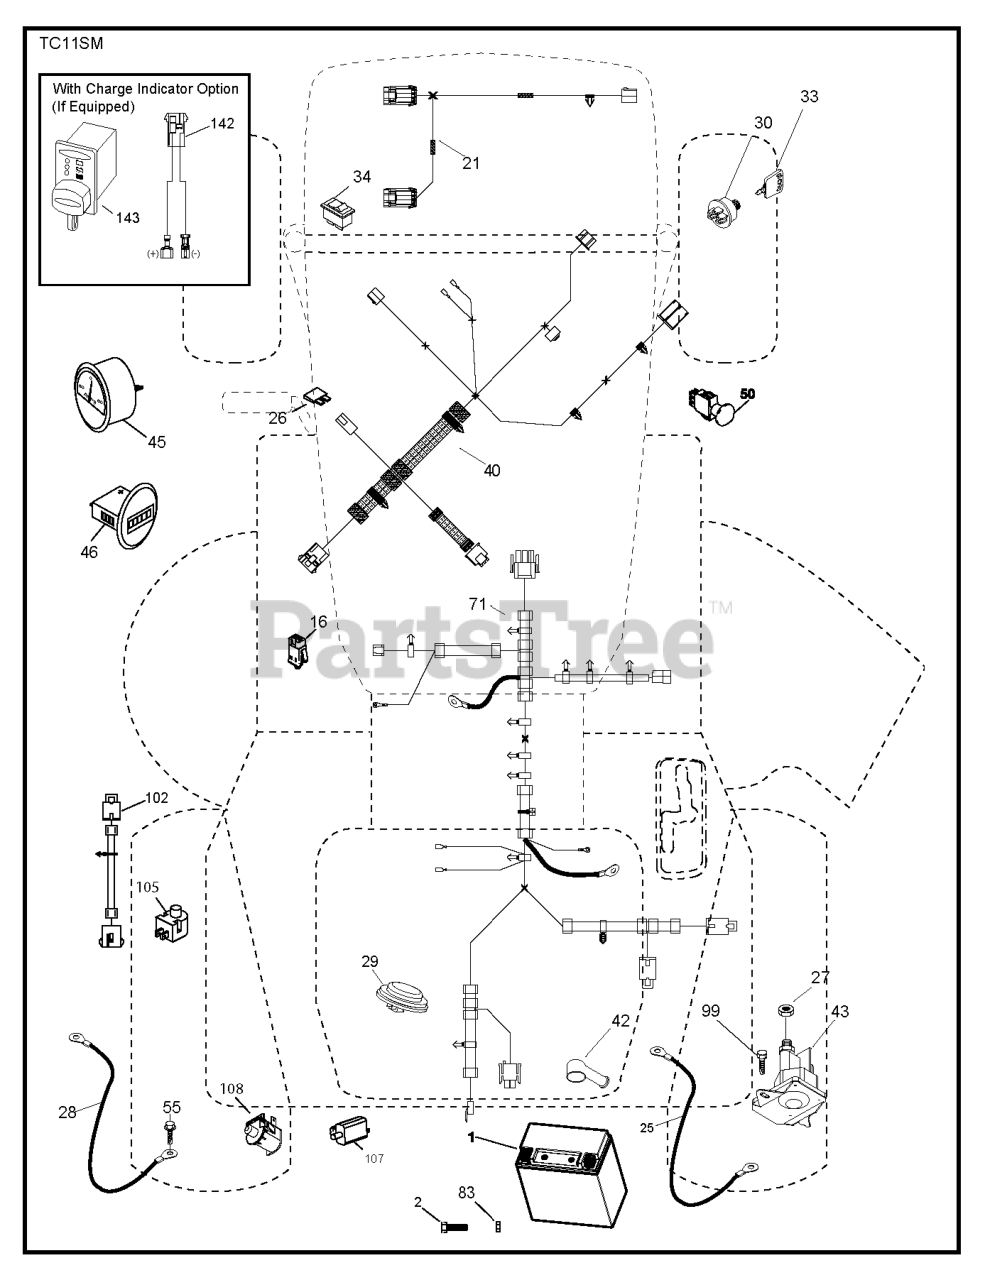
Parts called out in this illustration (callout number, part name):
1	BATTERY BATTERY 14AH 12V LEOC
16	SWITCH INTERLOOK PUSH-IN
21	HARNESS LIGHT ASSY TRACTOR,
25	CABLE.BATT.8GA.RED9.CRD2.5
26	FUSE 20AMP
28	CABLE.BATT.BLCK10.SLV.CRD2.5
29	SWITCH.SEAT.DELTA.OPC.
30	SWITCH.IGN.DELTA.W.LGH.ROS
33	KEY.CHAIN.BLISTER.PACK.GEN.INT
40	HARNESS.DASH.TCRD.EL.RND.CH.RS
42	TERMINAL COVER
50	RP SWITCH.PTO.TERMINAL.STD.RED
55	SCREW 5/16"
71	HARNESS
83	NUT SQUARE M6, 11X8.5 ZPB
99	SCREW
102	HARNESS ASSY
105	REVERSE SWITCH
107	.WITCH.FULL BAGGER.INDICATOR
108	SWITCH.SNPMT.NCBT.CRD.MTL.BKPL
142	CHARGE.PORT.PIGTAIL HARNESS
143	CHARGE.PORT
